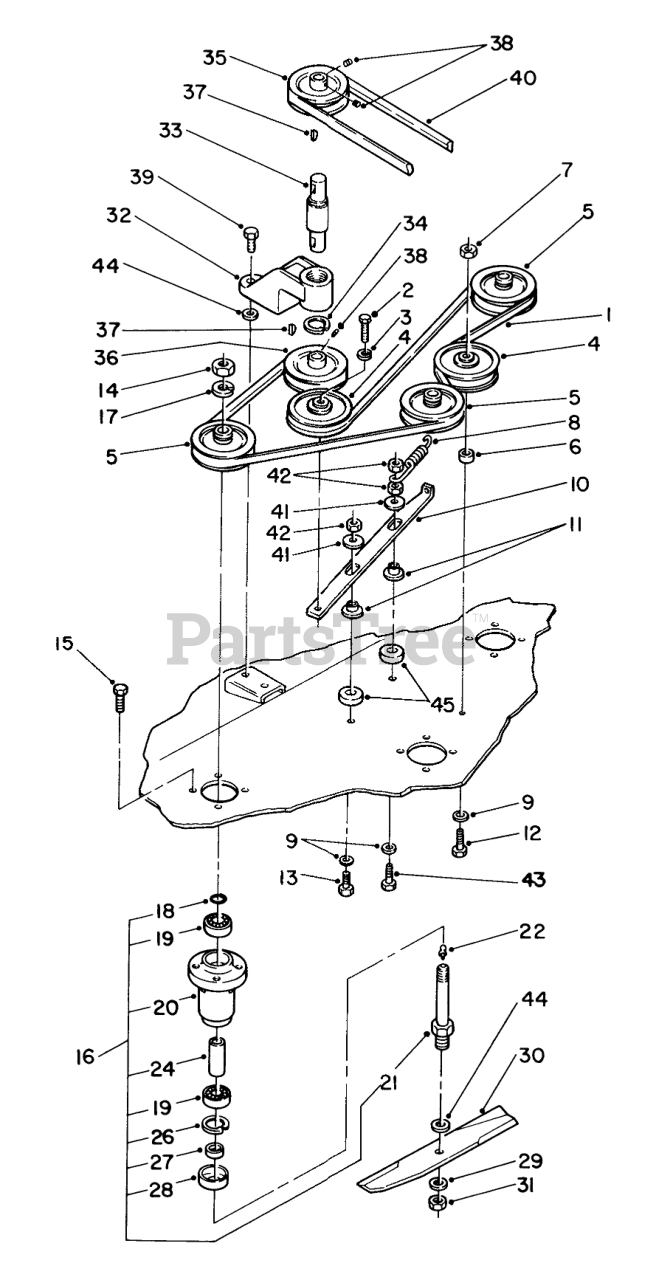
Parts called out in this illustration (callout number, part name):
1	V-BELT
1	ASSY 42" MOWER RE R
2	SCREW-HH
3	WASHER-LOCK
4	PULLEY-IDLER
5	PULLEY
6	SPACER
7	NUT-LOCK, NI
8	SPRING-EXTENSION
9	WASHER
10	BAR-SLIDER
11	SPACER-BUSHING
12	SCREW-HH
13	SCREW-HH
14	NUT-JAM
15	Bolt
16	Assembly-Spindle
17	Lockwasher
18	O RING
19	BEARING-BALL
20	HOUSING-SPINDLE
21	SHAFT-SPINDLE
22	Zerk
26	RING-RETAINING
27	SPACER-BLADE
28	CUP-SPINDLE
29	Washer-Plain
30	Blade 14.5 Low Lift
31	NUT-JAM
32	Jack Shaft Housing
33	BEARING-INT SHAFT
34	RING-SNAP
35	PULLEY
36	PULLEY-SPLIT
37	KEY-WOODRUFF
38	SCREW-SET, HSH
39	Bolt
40	V-BELT
41	WASHER
42	NUT-LOCK, NI
43	SCREW-HH
44	Washer
45	SPACER
